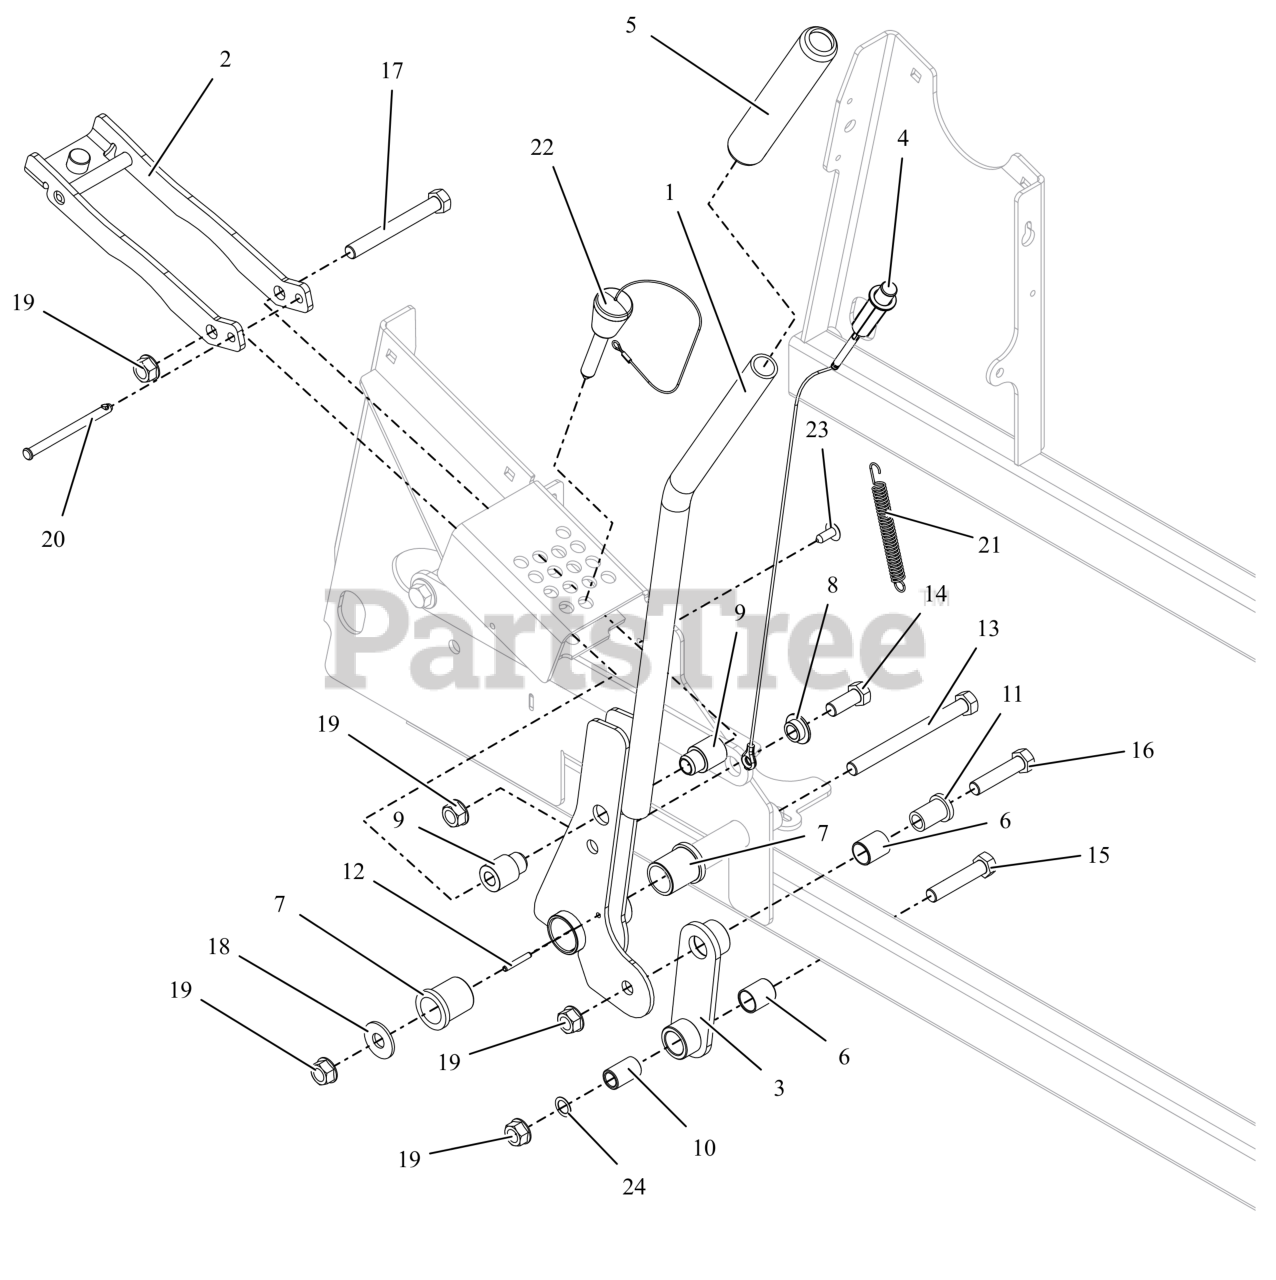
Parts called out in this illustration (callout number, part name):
1	WLDMT, HOC LEVER
2	WLDMT, HOC BRACKET
3	LINK, HOC LEVER
4	CABLE, HOC PUSH CONTROL
5	GRIP, DECK LIFT
6	BRG, .750 X .875 X 1.000
7	BSHG-FLG 1.00X1.25X1.50X1.50
8	BSHG, FLG .515X.750X.360X1.12
9	BSHG,FLG
10	SPCR, SLV .532 X .750 X 1.150
11	BSHG-FLG .515X.746X1.290X1.000
12	PIN-ROLL .188X1.25
13	BLT,HEX .50-13X5.50 G5 ZCC
14	BLT,HEX .50-13X1.25 G5 ZCC
15	BLT, HEX .50-13X2.50 G5 ZCC
16	BLT, HEX .50-13X2.25 G5 ZCC
17	BLT, HEX 0.5-13X4.25 GR5 ZCC
18	WSHR,FLT .563X1.375X.109 ZCC
19	NUT-LK-CTR-FLG .500-13 GG ZCC
20	PIN, SLIC-.3125X4.015X3.625 -ZCC
21	SPRING,EXT,.061X.50X3.0
22	PIN- MAGNETIC .50X2.70
23	XMAS TREE FASTNER-BLACK
24	WASHER, .500X.750X.020 THRUST
